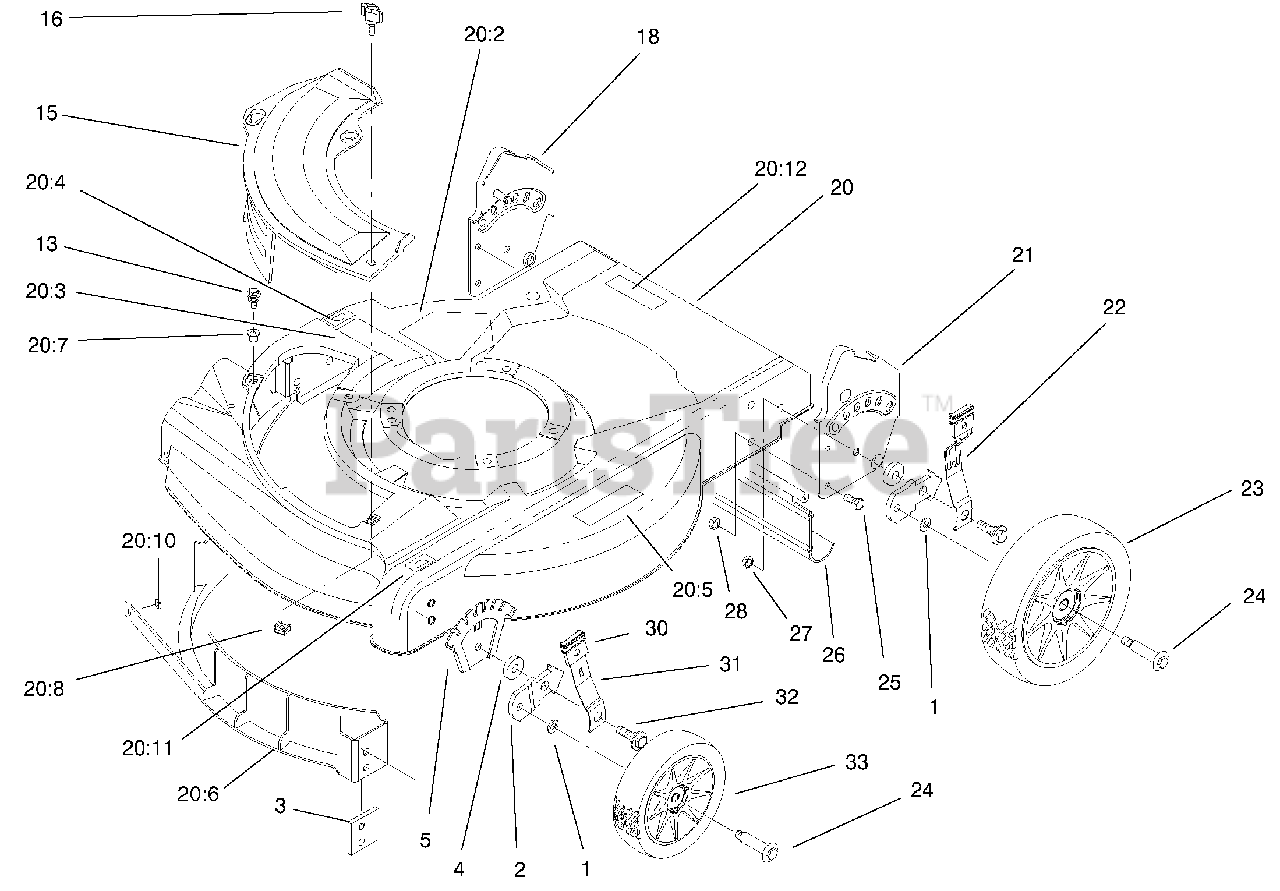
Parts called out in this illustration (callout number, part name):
2	BRACKET-HEIGHT ADJUSTMENT, WHEEL
3	PLATE - BAFFLE
4	WASHER-WHEEL
5	PLATE - HEIGHT ADJUSTMENT
13	SCREW-SEMS
15	PLATE-MULCH
18	RH HANDLE BRKT ASM
20	Housing ASM (only on: 10270)
20	Housing-Service (only on: 10270c)
20:2	Decal-Danger (only on: 10270)
20:2	Danger Decal(Fr/E)(only on: 10270c)
20:3	Decal-Warning (only on: 10270)
20:3	Decal-Warning (only on: 10270c)
20:4	Decal-HOC, RH (only on: 10270)
20:4	Decal-HOC,RH (only on: 10270c)
20:5	Decal-Warning (only on: 10270)
20:5	Decal-Warning (only on: 10270c)
20:6	Insert-Housing
20:7	GROMMET - PLASTIC
20:8	NUT-CAGE
20:10	WASHER-FLAT
20:11	Decal-HOC, LH (only on: 10270)
20:11	Decal-HOC,LH (only on: 10270c)
20:12	Decal-Manual,Lb (only on: 10270c)
21	LH HANDLE BRKT ASM
22	SPRING ARM ASM - REAR
23	WHEEL & TIRE 8"
24	BOLT-SHOULDER
25	SCREW-HH
26	SHIELD - TRAILING
27	NUT-LOCK, NI
28	NUT-LOCK, NI
30	KNOB-LEVER, HEIGHT ADJUSTMENT
31	ARM-FRONT SPRING
32	BOLT-SHOULDER
33	WHEEL & TIRE 6"
